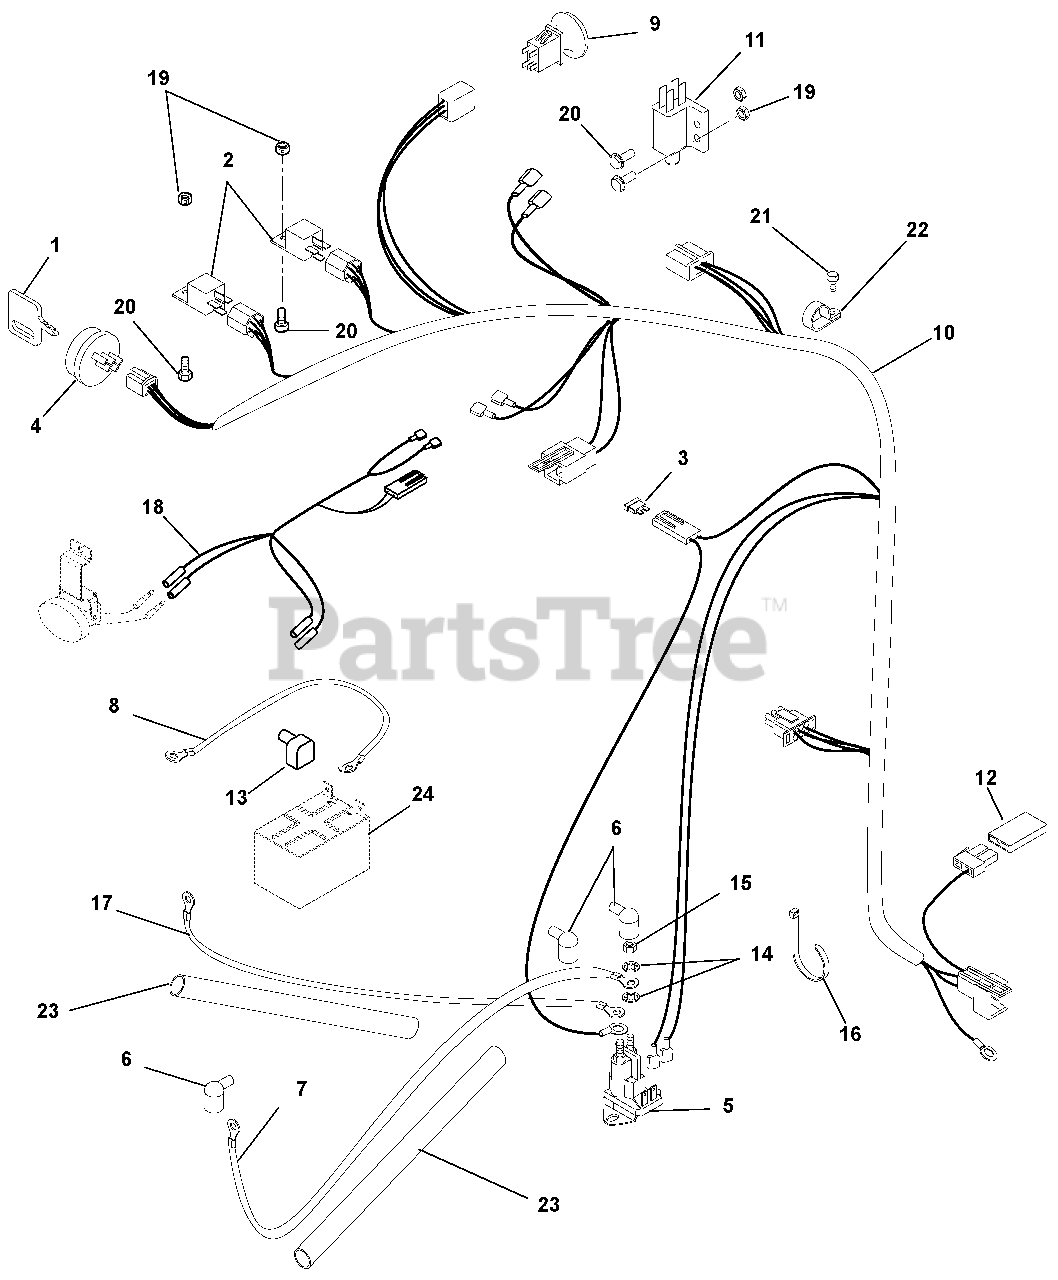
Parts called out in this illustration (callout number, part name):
1	Key with Cap
2	Relay
3	Fuse, 30 AMP
4	Key Switch
5	Solenoid
6	Boot, Eyelet Terminal
7	Starter Cable
8	Cable, Ground .25 x 13.00 x .31
9	Switch, Clutch With Retainer
10	Harness, ZTXL/ZoomXL
11	Switch, Double Pole N.O. / N.O.
12	Diode, Connector Shell
13	Insulator
14	Washer, Locking .31
15	Nut, Jam .31-24
16	Cable Tie
17	Starter Cable
18	Harness, Headlight
19	Nut, Locking Nylon With Insert 10-24
20	Screw, Hex Washer Head Machine 10-24 x .75
21	Screw, Tapping Hex Washer Head Thread Rolling .38-16 x .50
22	Clamp, Cushioned Steel .75
23	Sleeve, Anti-Abrasion
24	Battery, 12V, 215 CCA GEP
